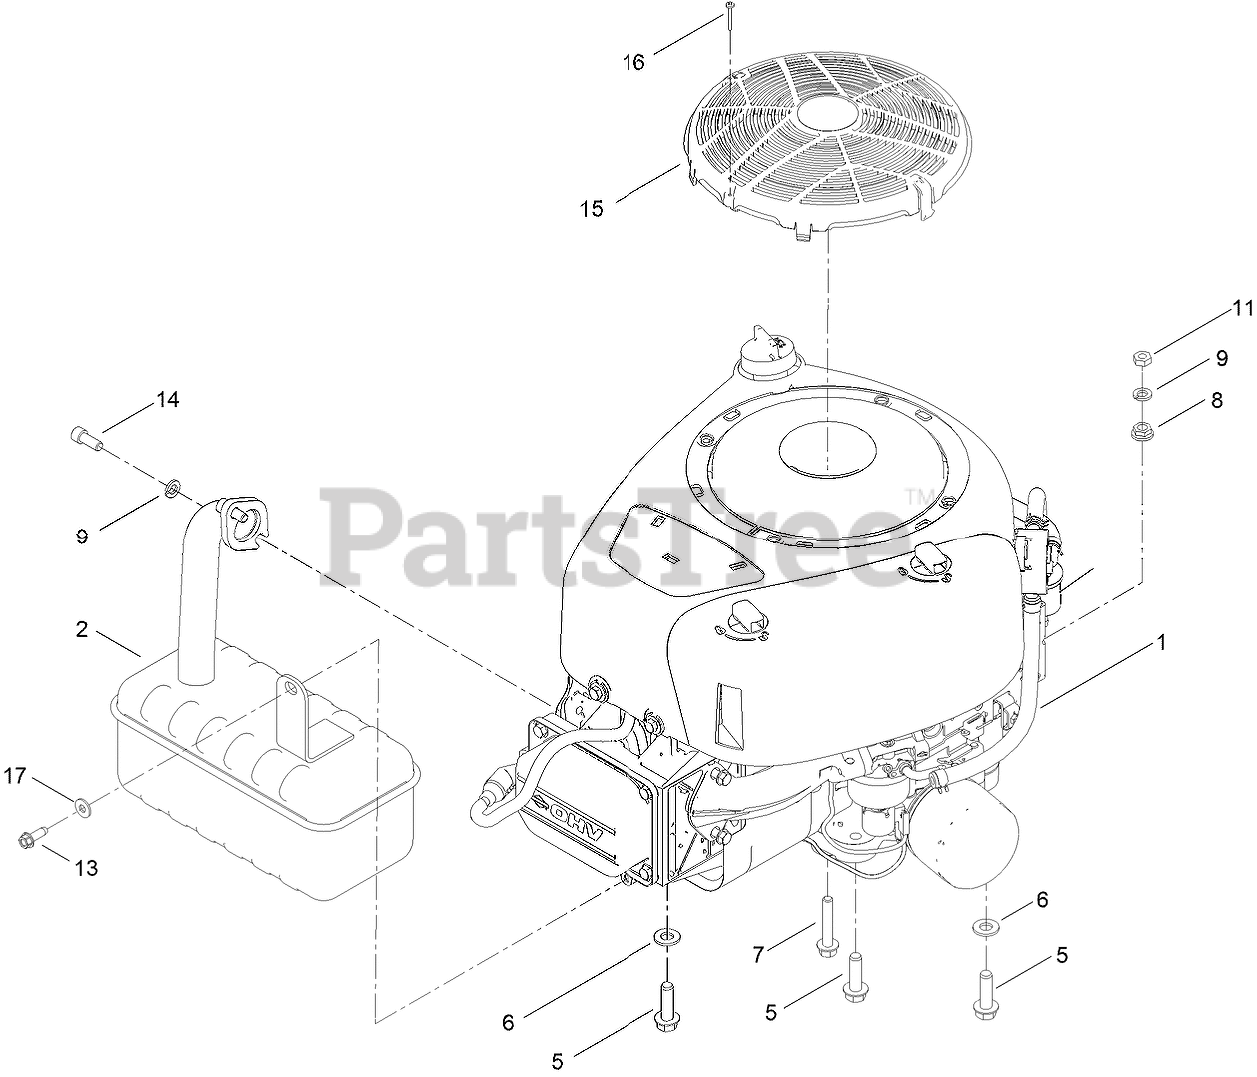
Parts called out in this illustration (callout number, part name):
1	ENGINE-BRIGGS, 1550 SERIES
2	MUFFLER
5	SCREW-HWH, THD ROLL
6	WASHER-FLAT
7	SCREW-HWH
8	NUT-HF
9	WASHER-LOCK
11	NUT-JAM
13	SCREW-HWHTF
14	SCREW-HSH
15	COVER-FAN
16	SCREW-FAN
17	WASHER
